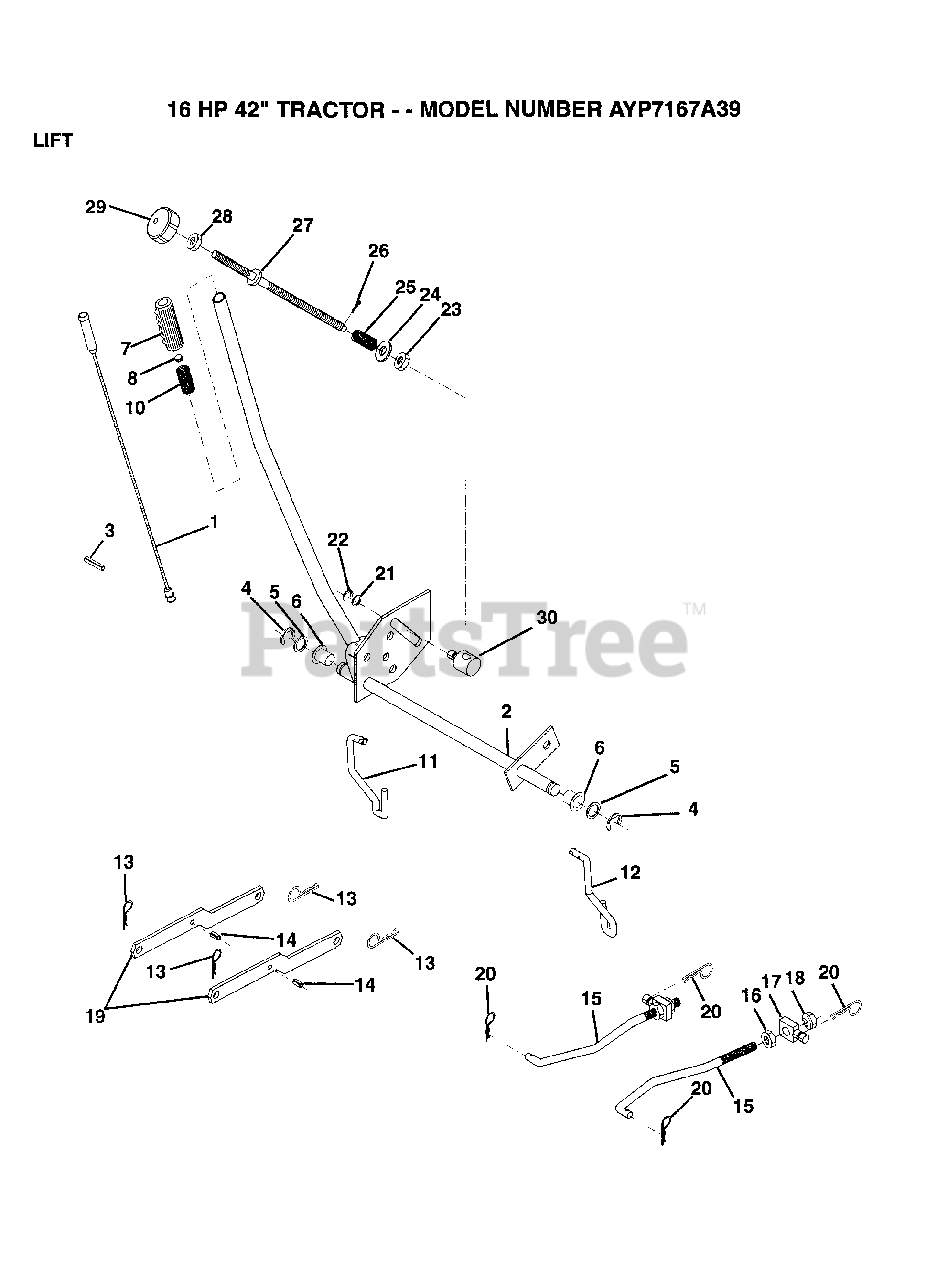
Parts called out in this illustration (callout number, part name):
1	WIRE ASM
2	SHAFT.ASM.LIFT LH
3	PIN GROOVE
4	E-RING
5	WASHER
6	NYLON BEARING
7	GRIP
11	LINK LIFT LH
12	LIFT LINK RH
14	"PIN,SPRING"
15	LINK.FRONT
16	NUT
17	TRUNION
18	NUT.LK.W/WSH.1/2.
20	RETAINER.SPRING
21	WASHER
22	KLIP RING
23	NUT T
24	WASHER
25	SPRING T
27	ROD LIFT LT
28	NUT
29	KNOB INF 3/8-16
30	TRUNION LT
